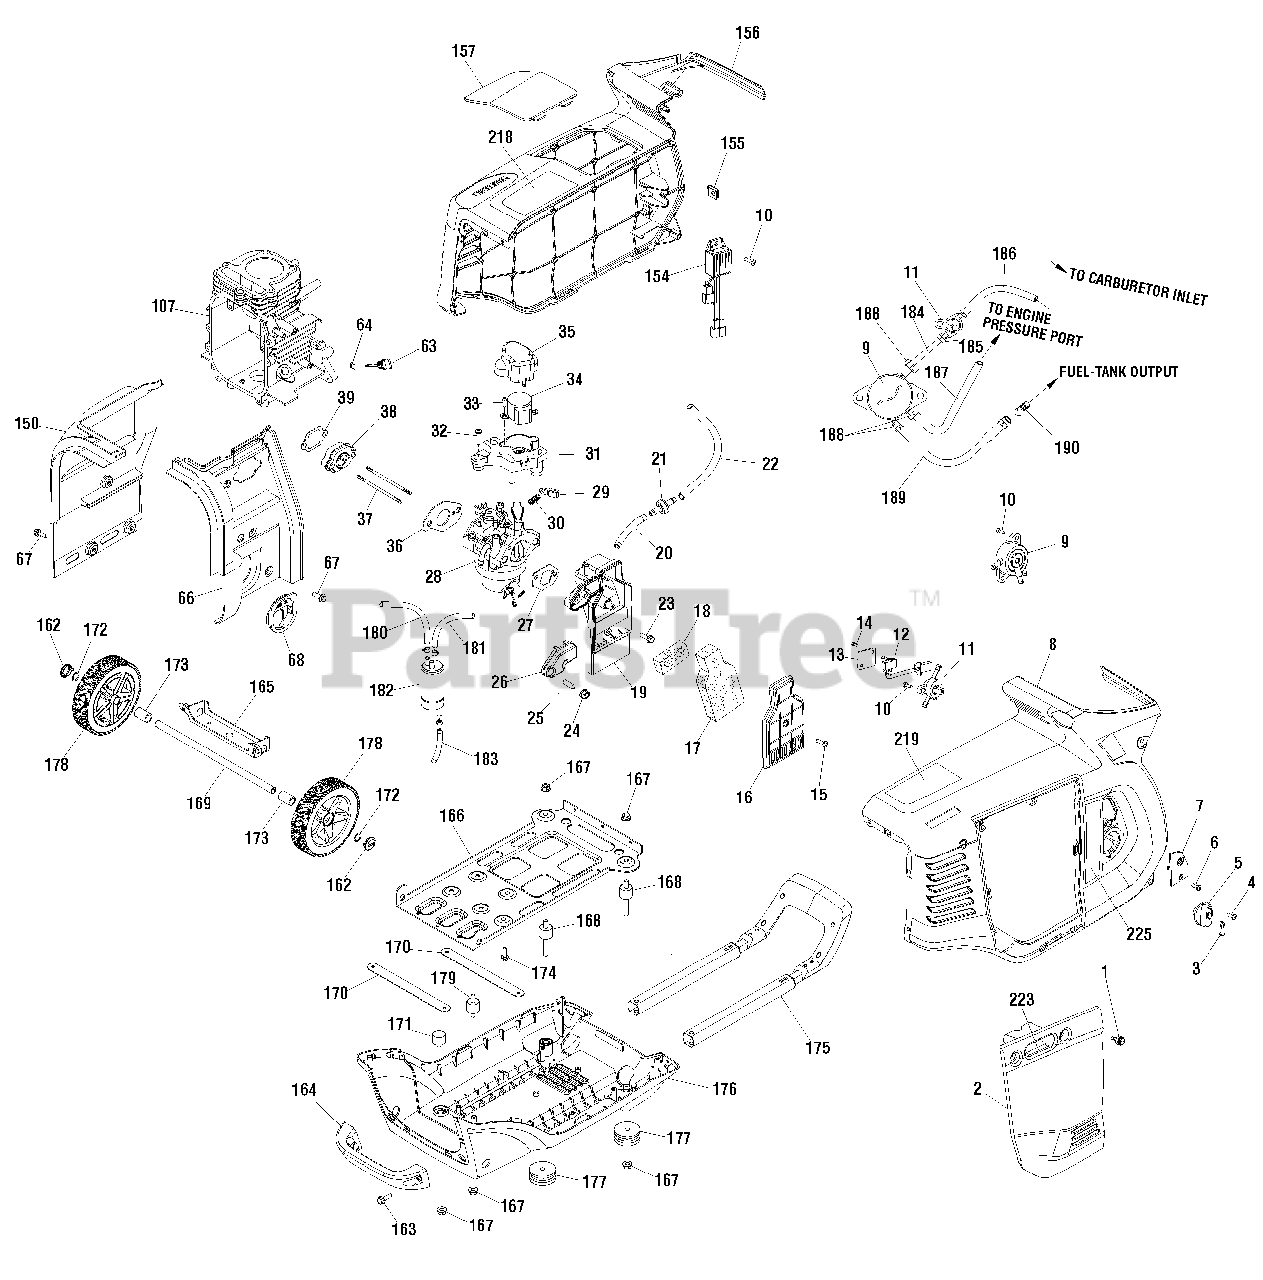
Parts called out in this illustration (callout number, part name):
4	SCREW
6	SCREW
10	SCREW
13	COVER-SWITCH
14	SCREW
16	COVER-AIR CLEANER
17	FILTER-A/C FOAM
18	FILTER-A/C FOAM
19	BASE-AIR CLEANER
24	NUT
25	SLEEVE
26	COVER-AIR CLEANER
27	GASKET-AIR CLEANER
30	SPRING
32	SCREW
33	SCREW
34	MOTOR-STEPPER
66	DEFLECTOR
67	BOLT-M6 x 12
68	SEAL-RUBBER
107	CRANKCASE
150	DEFLECTOR
154	REGULATOR-VOLTAGE
155	NUT
157	COVER-SPARK PLUG
163	BOLT-M6 x 25
167	NUT-FLANGE M8
168	MOUNT-VIBRATION
171	MOUNT-VIBRATION
172	CLIP
174	BOLT-M8 x 16
177	MOUNT-VIBRATION
179	MOUNT-VIBRATION
185	CLAMP
188	CLAMP
